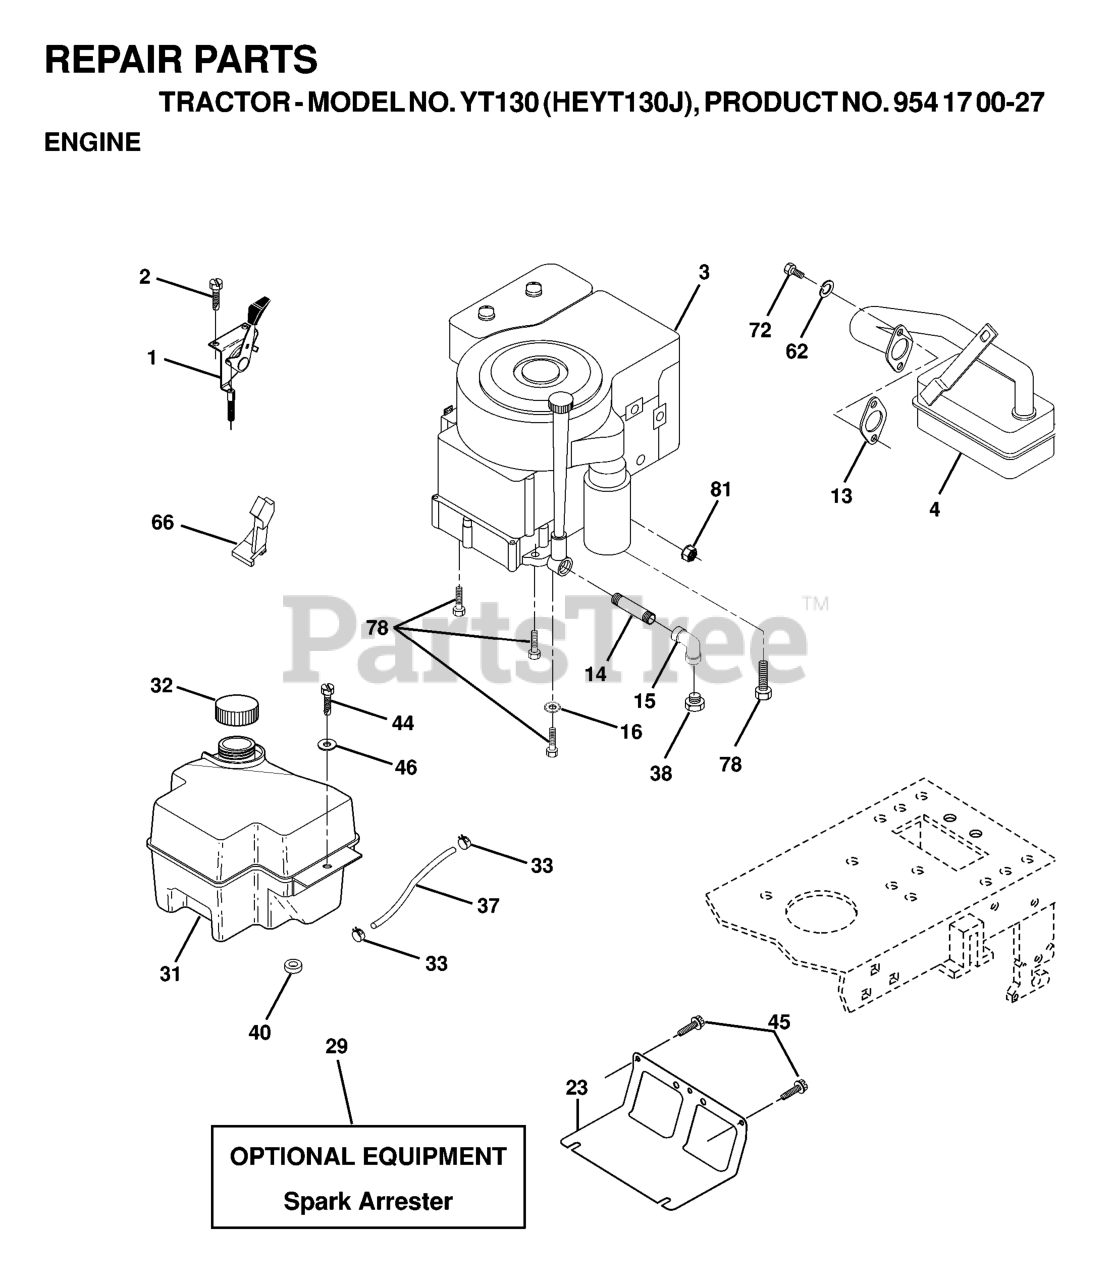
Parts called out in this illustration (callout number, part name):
1	CONTROL
2	SCREW LT
4	MUFFLER.SINGLE.B&S.10-12HP
13	REPL BY 532 27 22-93
14	Nipple Pipe 3/8 Npt X 3-1/2
15	ELBOW
16	LOCKWASHER
23	SHIELD.BROWNING.DBR.GUARD
29	KIT.SPARK ARRESTOR 794945 B&S
31	FUEL TANK
32	FUEL CAP
33	HOSE CLAMP
37	LINE.FUEL.20
40	BUSHING.SNAP.NYL.BLK.
44	SCREW HEX CRT
45	SCREW 3/8-16X3/4
62	WASHER.LOCK.HVY.HLCL.SPR.5/16
66	STOP THROTTLE
72	Screw, Hex.Hd. Cap 5/16 - 18 x 5/8
78	SCREW.3/8-16
81	NUT FLANGE 1/4-20 STARTER NUT
